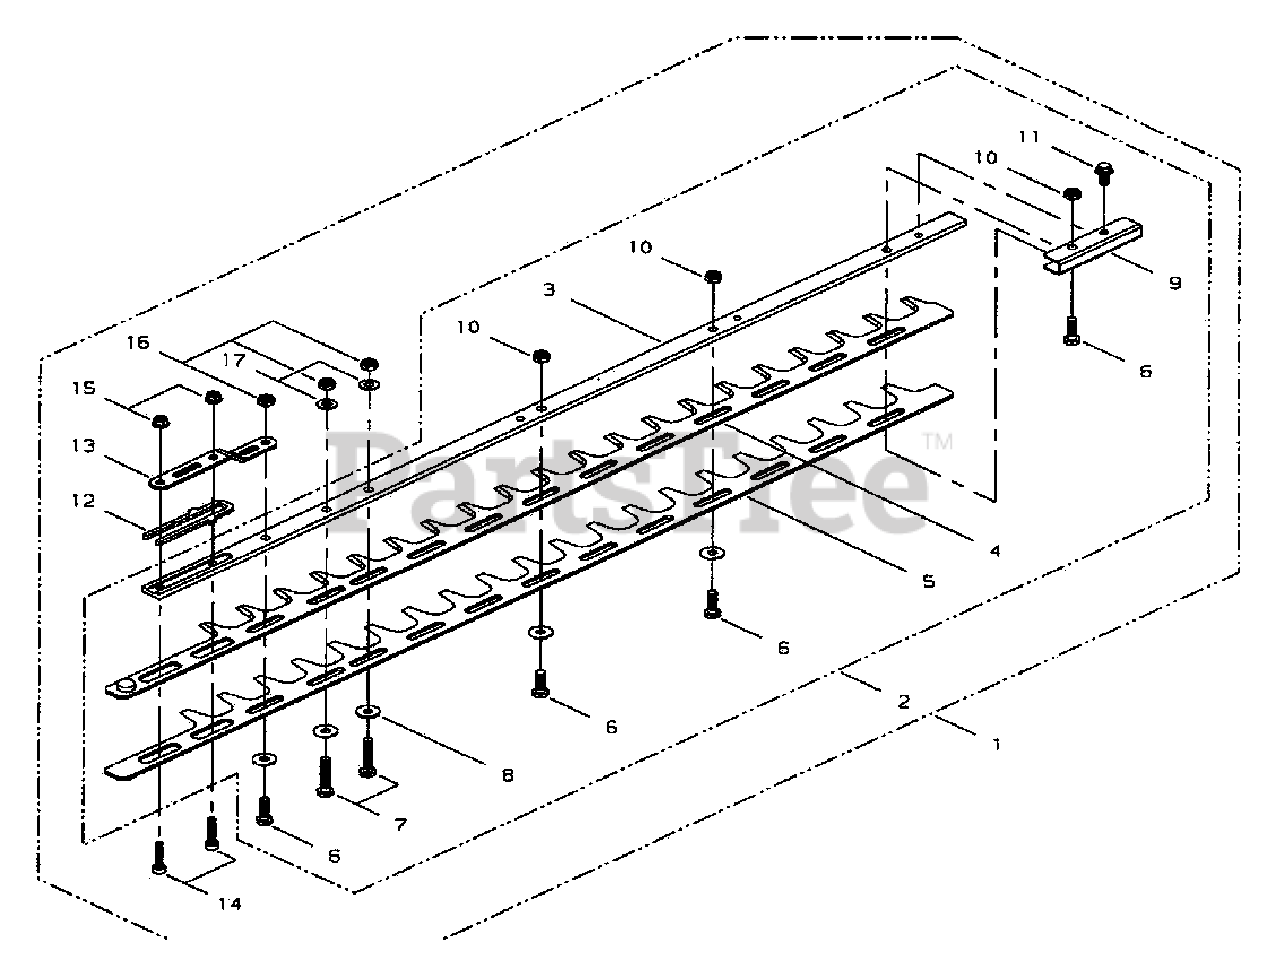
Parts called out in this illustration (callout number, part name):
1	CUTTER KIT, 30" HD
2	CUTTER ASSY, 30" HD
3	GUIDE BAR, 30"
4	CUTTER, 30" HD UPPER
5	CUTTER, 30" HD LOWER
6	BOLT M6×20
7	BOLT M6×32
8	WASHER M6
9	PLATE, GUIDE
10	NUT M6
11	BOLT M5×8
13	BRACKET, CUTTER
14	BOLT 5×25
15	NUT M5
16	NUT M6
17	WASHER 6.5×13×1
